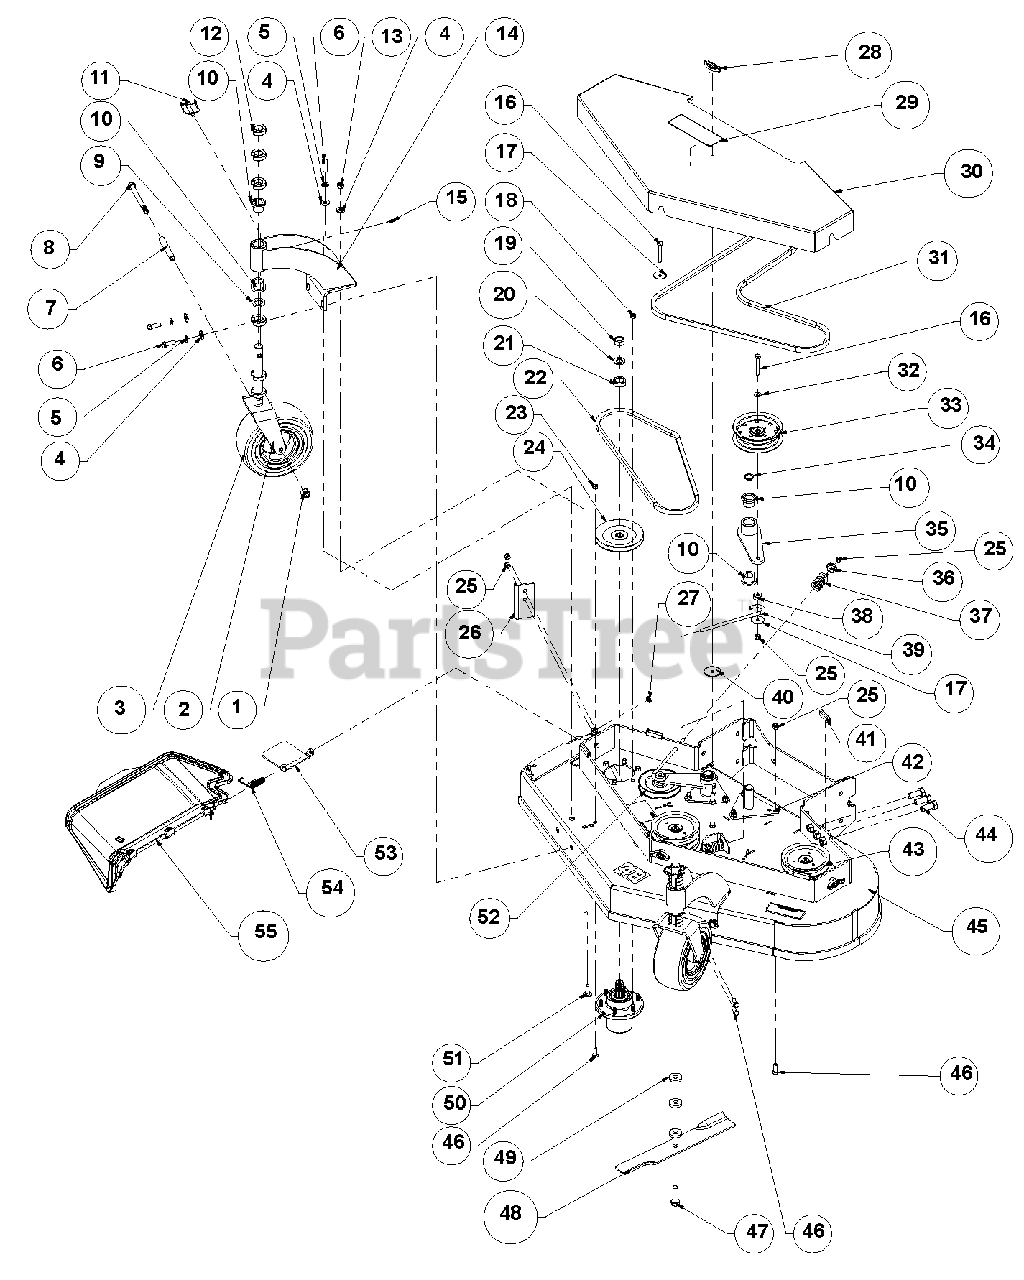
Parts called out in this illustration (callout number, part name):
1	Locknut, .50-13 Nyloc
2	Weldment, Caster Yoke w/EverRide Paint
3	Assembly, Wheel and Tire 9 x 3.5
4	Washer, .375 Regular Flat
5	Washer, .438 Medium Spring Lock
6	Bolt, .4375-14 x 1.25 Hex 5
7	Tube, Caster Axle
8	Bolt, .50-13 x 5.50 Hex 5
9	Bushing, 1.03 x 1.50 x .179
10	Bearing, Flange 1.00 x 1.25 x 1.00
11	Pin, LNC .438 x 2.00
12	C-Spacer, 1.00 x 1.77 x .500
13	Locknut, .4375-14 Crown
14	Weldment, Caster Support w/EverRide Paint
15	Fitting, .25-28 Straight Grease Zerk
16	Bolt, .38-16 x 2.50 Hex 5
17	Washer, .375 x 1.50 x .063 Flat
18	Nut, .38-16 Standard Hex 5
19	Locknut, .75-16 Crown
20	Washer, .75 x 1.3125 x .120
21	Spacer, Spindle Top-Pulley
22	Belt, HB 51.4 Elbow AMD
23	Locknut, .38-16 Crown
24	Pulley, Narrow Spline
25	Locknut, 3/8-16 Nyloc
26	Plate, Extender
27	Retainer
28	Knob, .38-16 Insert
29	Decal, 9" EverRide Logo
30	Weldment, 48" Belt Shield EverRide
31	Belt, HB 77.5 Elbow AMD OHR
32	Washer, .406 x .813 x .065 Flat
33	Pulley, Flat 5.00X.375 W/BRG
34	Snap Ring, 1.00 x .042 External
35	Weldment, Idler Arm
36	Keeper, Spring
37	Spring, COM 1.22 x .162 x 2.50
38	Bushing, .380 x 1.00 x .410
39	J-Bolt, .38-16 x 7.88
40	Washer, .402 x 2.00 x .055
41	Trim, 1/4" Trim-Lok Edge
42	Weldment, Idler Pivot Mount
43	Pulley, Spline Spindle LSE
44	Bolt, Hex .6250-11 1.5" Grade 8
45	48" EverRide Hydro Deck withDecals
46	Bolt, .38-16 x 1.00 Hex 5
47	Bolt, .625-11 x 2.00 Hex 8
48	Blade, 16.500 x .80 Lift
49	Washer, .630 x 1.50 x .250 Flat
50	Assembly, Spindle Housing
51	Bolt, .4375-14 x 1.25 Round Head Square Neck
52	Pulley, Idler 5.0 V-GROOVE
53	Bracket, Chute Support 48" Deck
54	Spring, Discharge Chute
55	Chute, Discharge Assembly
